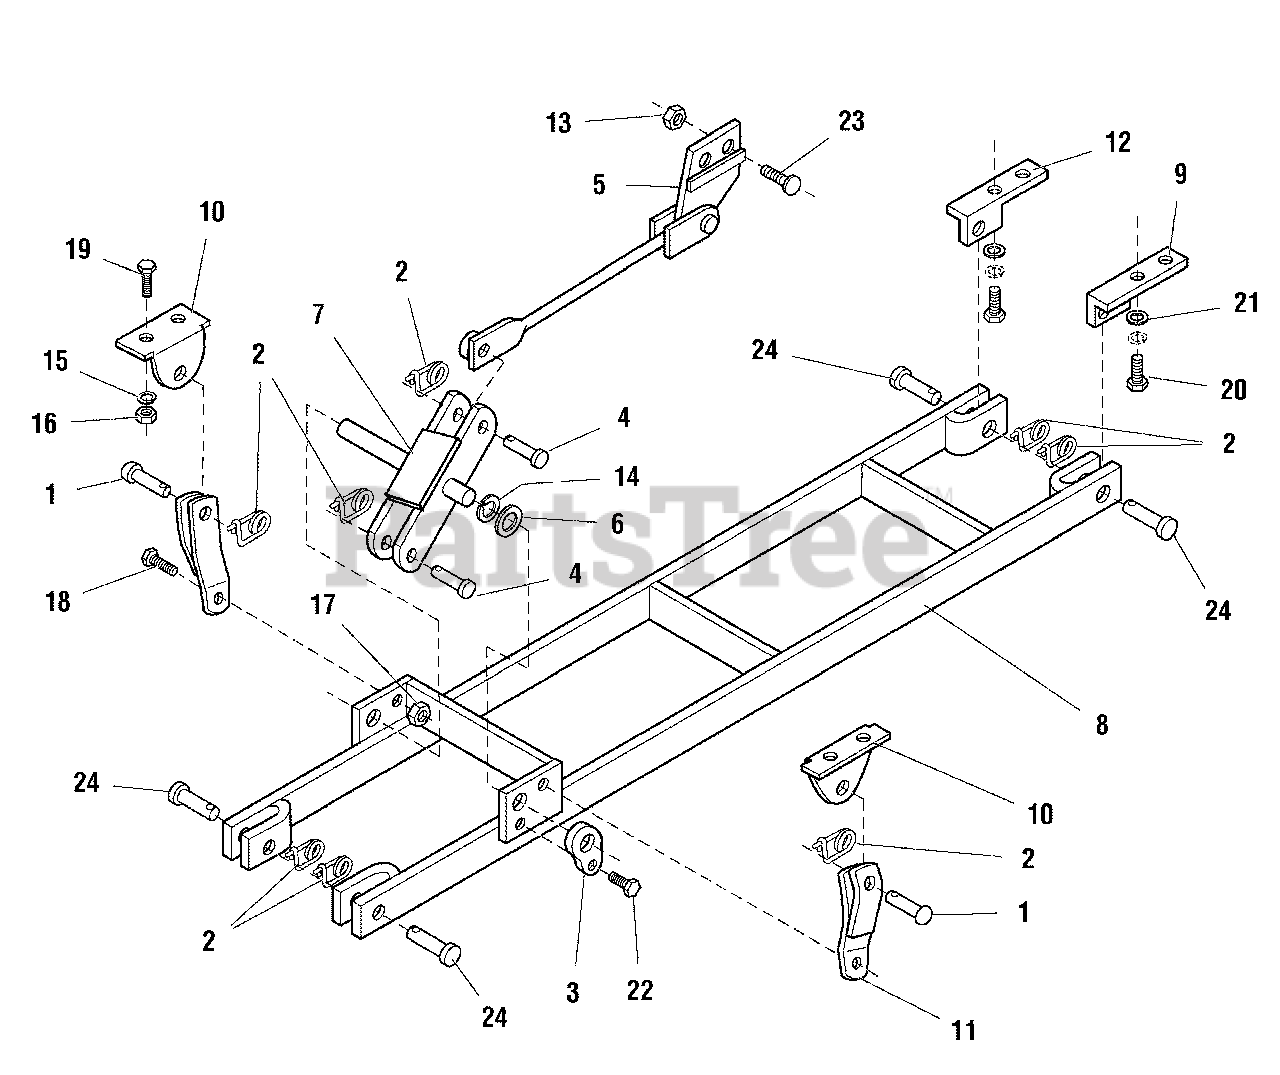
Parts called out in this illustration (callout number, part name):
1	PIN, Round Hd Clevis, 1/2 x 1-1/2
2	CLIP, Safety
3	BEARING, Lift Shaft
4	PIN, Flat Hd Clevis,1/2 x 2
5	ARM, Lift
7	SHAFT & LIFT ARM ASSEMBLY
8	HITCH ASSEMBLY
9	ANCHOR ASSEMBLY, LH
10	BRACKET, Front
11	BRACKET, Hanger
12	ANCHOR ASSEMBLY, RH
13	NUT, Hex, 3/8-16
14	RING, Retaining, 1"
15	WASHER, Lock, 5/16
16	NUT, Hex, 5/16-18
17	NUT, Hex Nylon Lock, 3/8-16
18	CAPSCREW, Hex Hd, 3/8-16 x 1
19	CAPSCREW, Hex Hd, 5/16-18 x 1-1/4
20	CAPSCREW, Hex Hd, 5/8-11 x 2
21	WASHER, 5/8
22	CAPSCREW, Hex Washer Hd, Taptite, 5/16-18 x 1-1/4
23	CARRIAGE BOLT, 3/8-16 x 1
24	PIN, Clevis, 5/8 x 2-1/4
